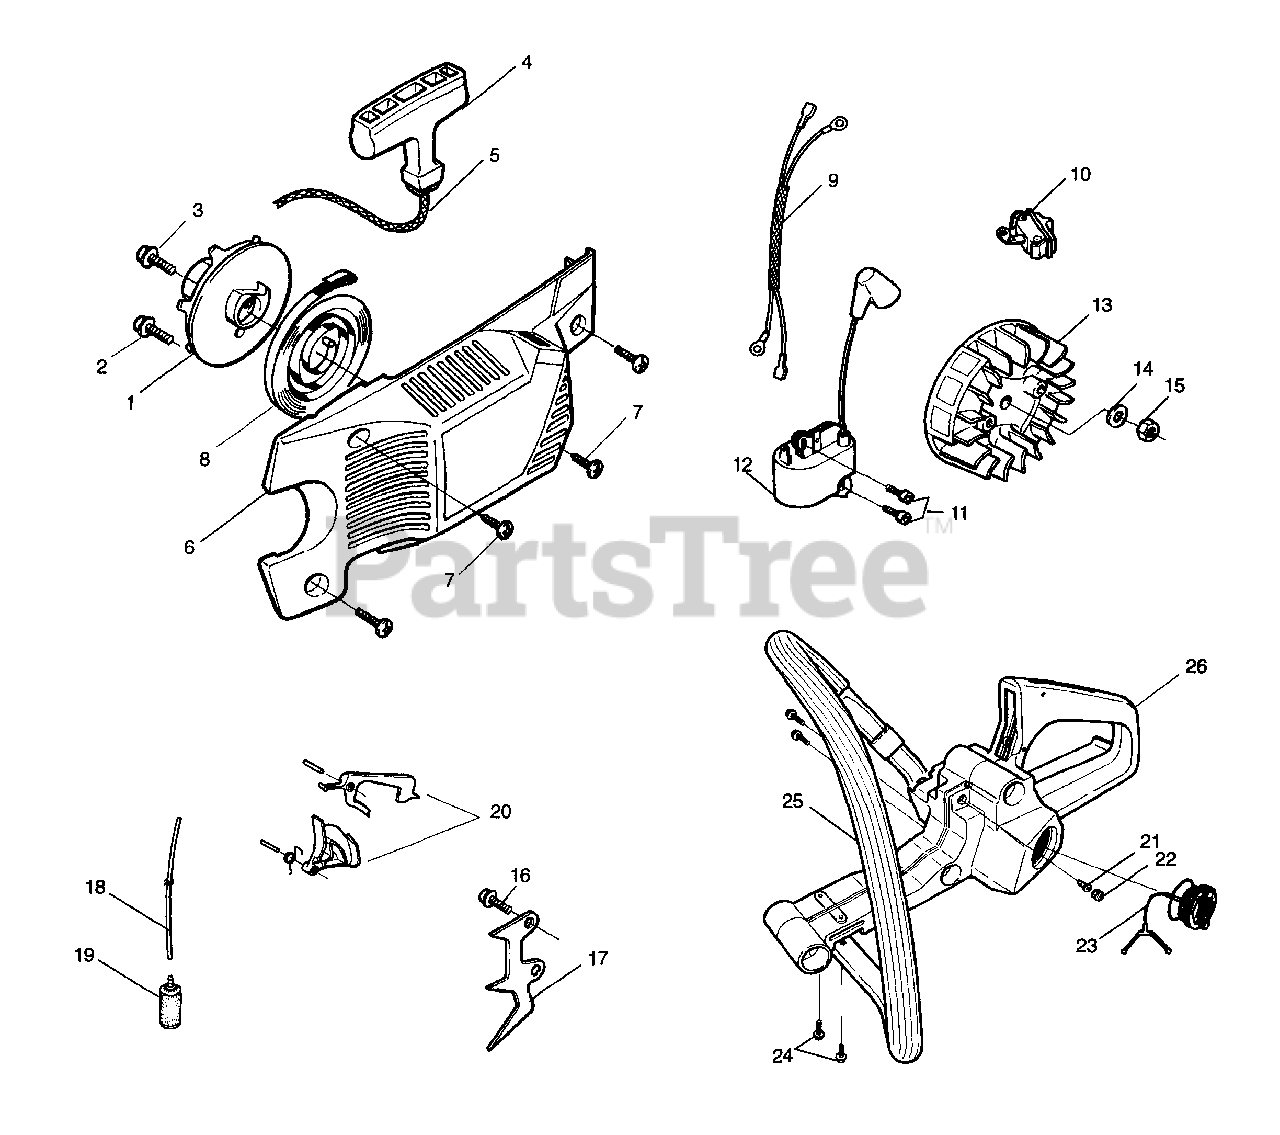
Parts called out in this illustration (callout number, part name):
1	Starter-Pulley Kit
4	Starter Handle
6	Fan Housing Assembly
8	Recoil Spring
9	Switch Wire Assy.
10	Ignition Switch
12	Ignition Module
13	Flywheel Assy.
14	Flywheel Washer
17	Spike Assy.
18	Fuel Line Kit
19	Fuel Pick-up
20	Throttle Trigger Kit
21	Check Valve
23	Fuel Cap
26	Tank & Handle Assembly
